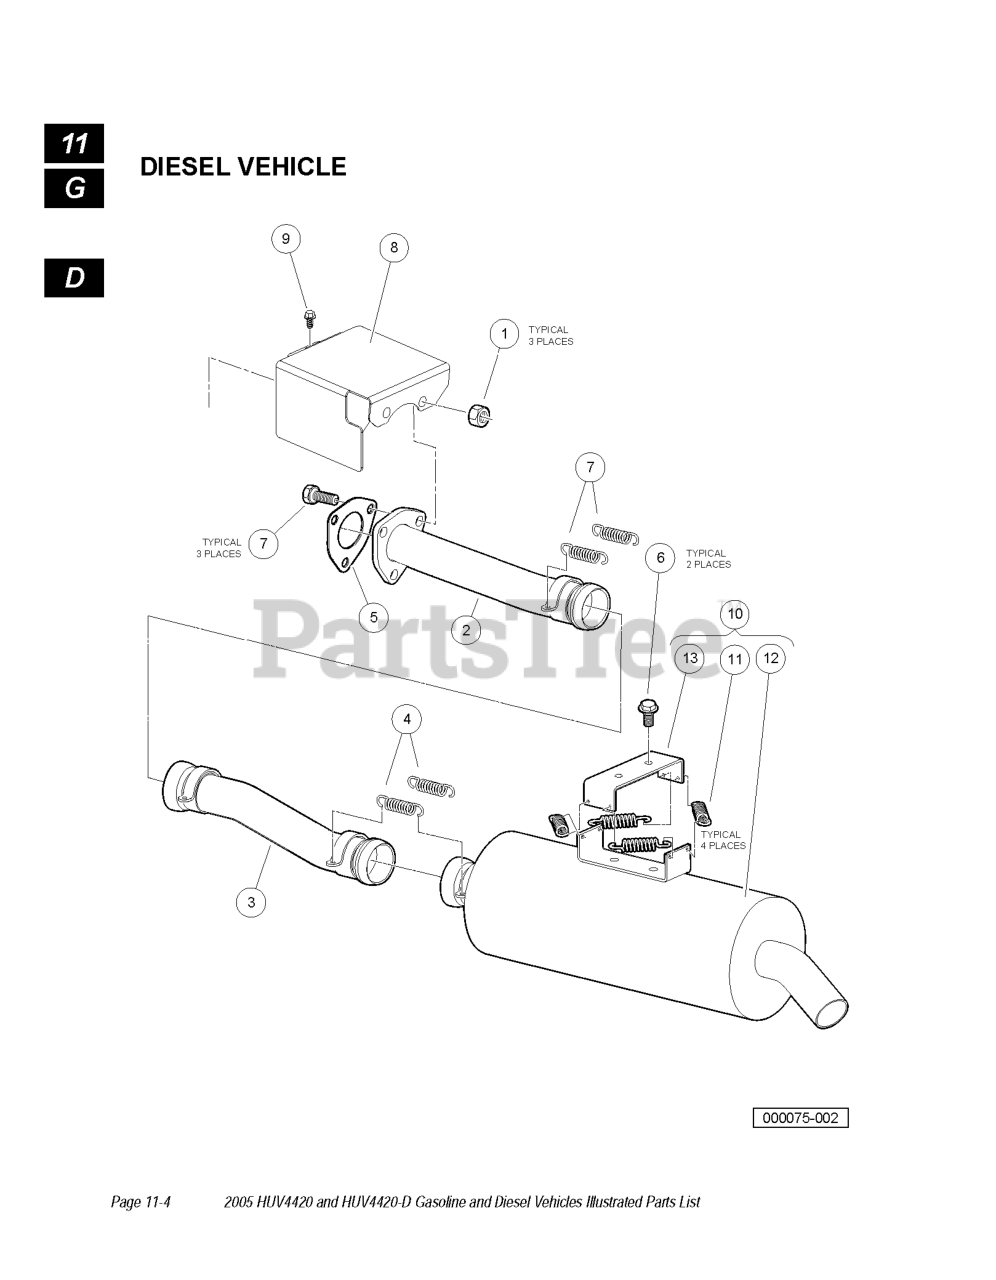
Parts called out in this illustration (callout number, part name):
1	NUT FLG, M8 X 1.25 MECH DEF
2	PIPE, EXHAUST DIESEL MAIN
3	PIPE, EXHAUST INTERMEDIATE
4	SPRING, EXHAUST
5	GASKET, EXHAUST DIESEL
6	BOLT FLG, M8X1.25X16 LOCTITE
7	BOLT, M8X1.25X40 LOCTITE
8	SHIELD, DIESEL EXHAUST
9	BOLT, D722, EXHST MANFLD COVER
10	ASM, MUFFLER, AWD HOMOLOGATION
11	SPRING, EXHAUST
